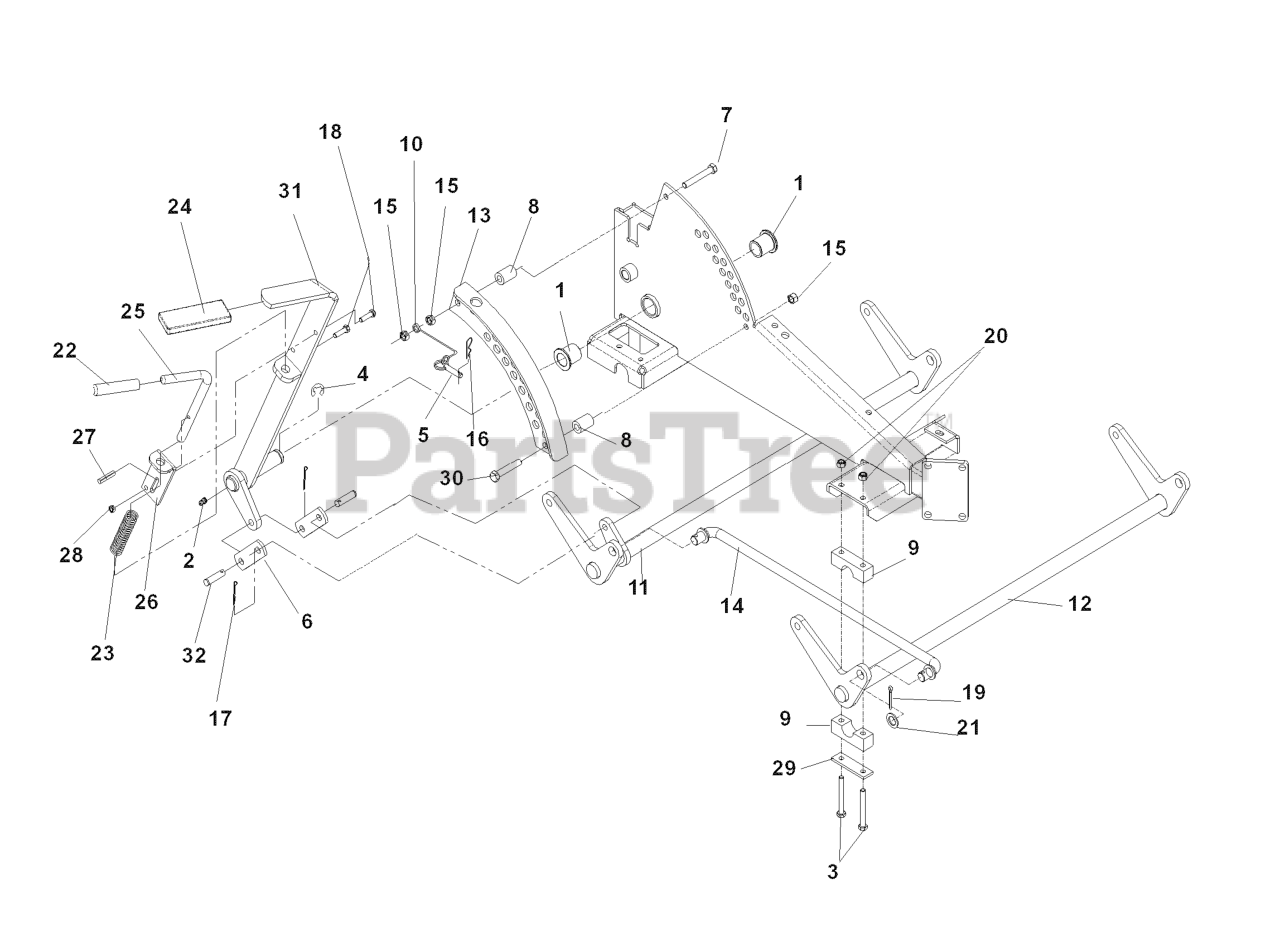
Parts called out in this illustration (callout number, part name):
1	BUSHING, FLANGED
2	ZERK
3	HCS 5/16C X 2-3/4
4	E-RING 7/8
7	SCREW 3/8C X 2 3/4 HEX CAP
8	DECK LIFT SPACER
9	PILLOW BLOCK
11	REAR LIFT SHAFT
12	FRONT LIFT SHAFT
13	ADJUSTMENT PLATE WLDMT
14	CROSS LINK
15	NUT 3/8-16 NYLOC
16	HAIRPIN #4
17	RP_COTTER PIN 1/8 X 3/4
18	HCS 1/4C X 3/4 HCS
19	COTTER PIN
20	NUT 5/16 NYLOC
21	BUSHING
26	PIN MT, UPPER
28	NUT 1/4C CENTER LOCK
29	REINFORCEMENT BAR
30	HCS 3/8C X 2 1/2
31	LIFT LEVER WELDMENT
32	CLEVIS PIN 3/8 X 1 1/8
